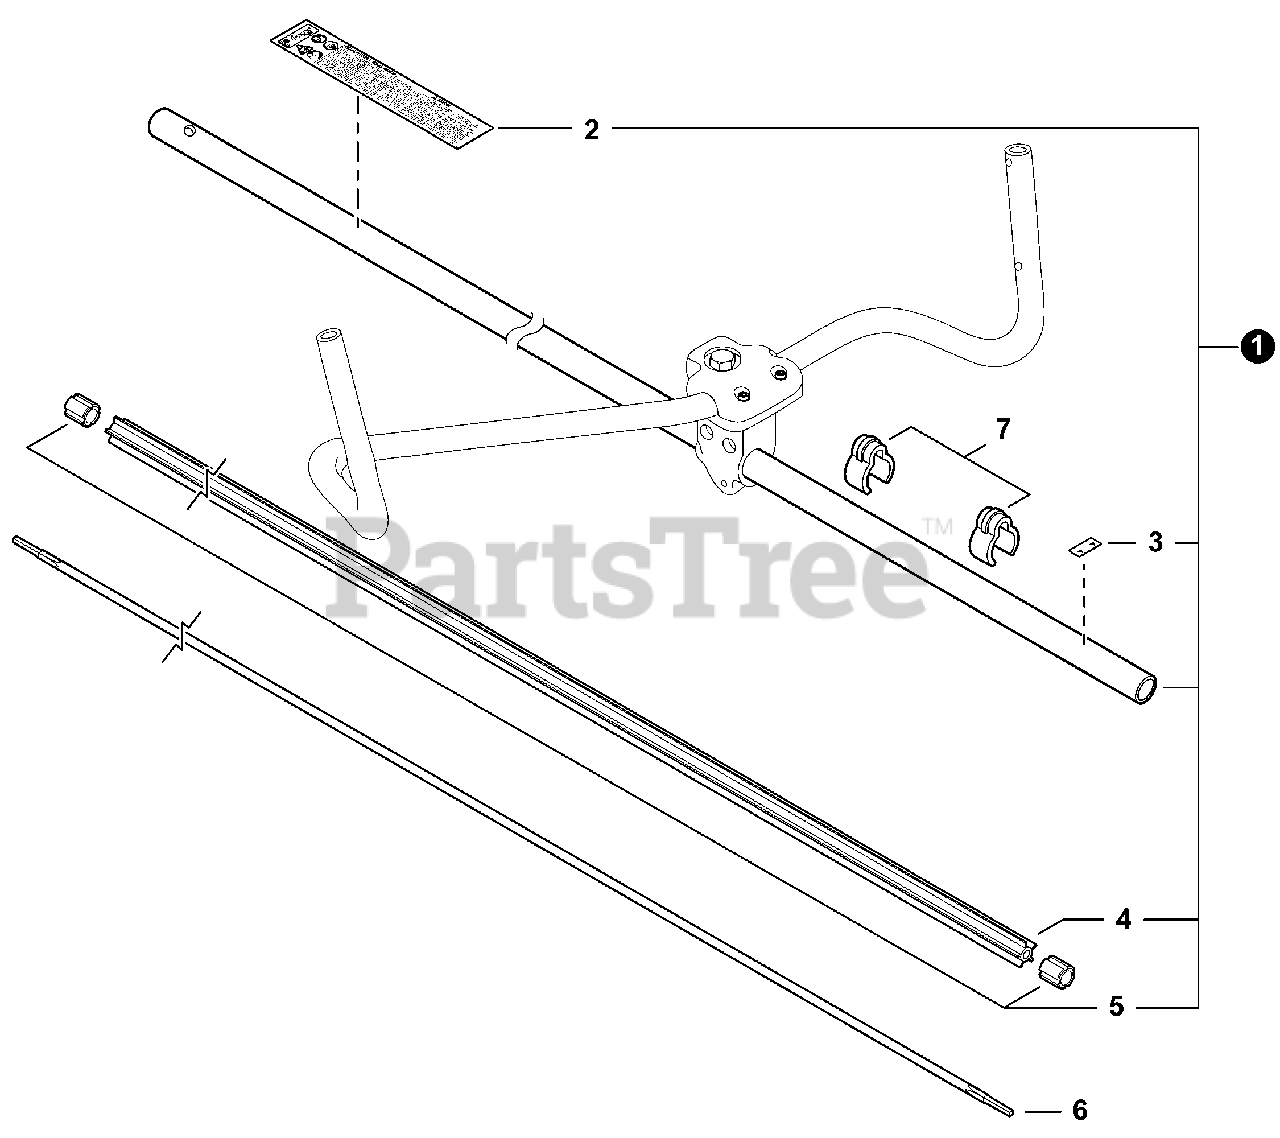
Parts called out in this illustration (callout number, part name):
1	MAIN PIPE ASSY
2	LABEL, CAUTION
3	LABEL - ALIGNMENT
4	LINER, FLEXIBLE 21.6×1420
6	DRIVESHAFT - FLEXIBLE
7	CLIP, CABLE 25MM
